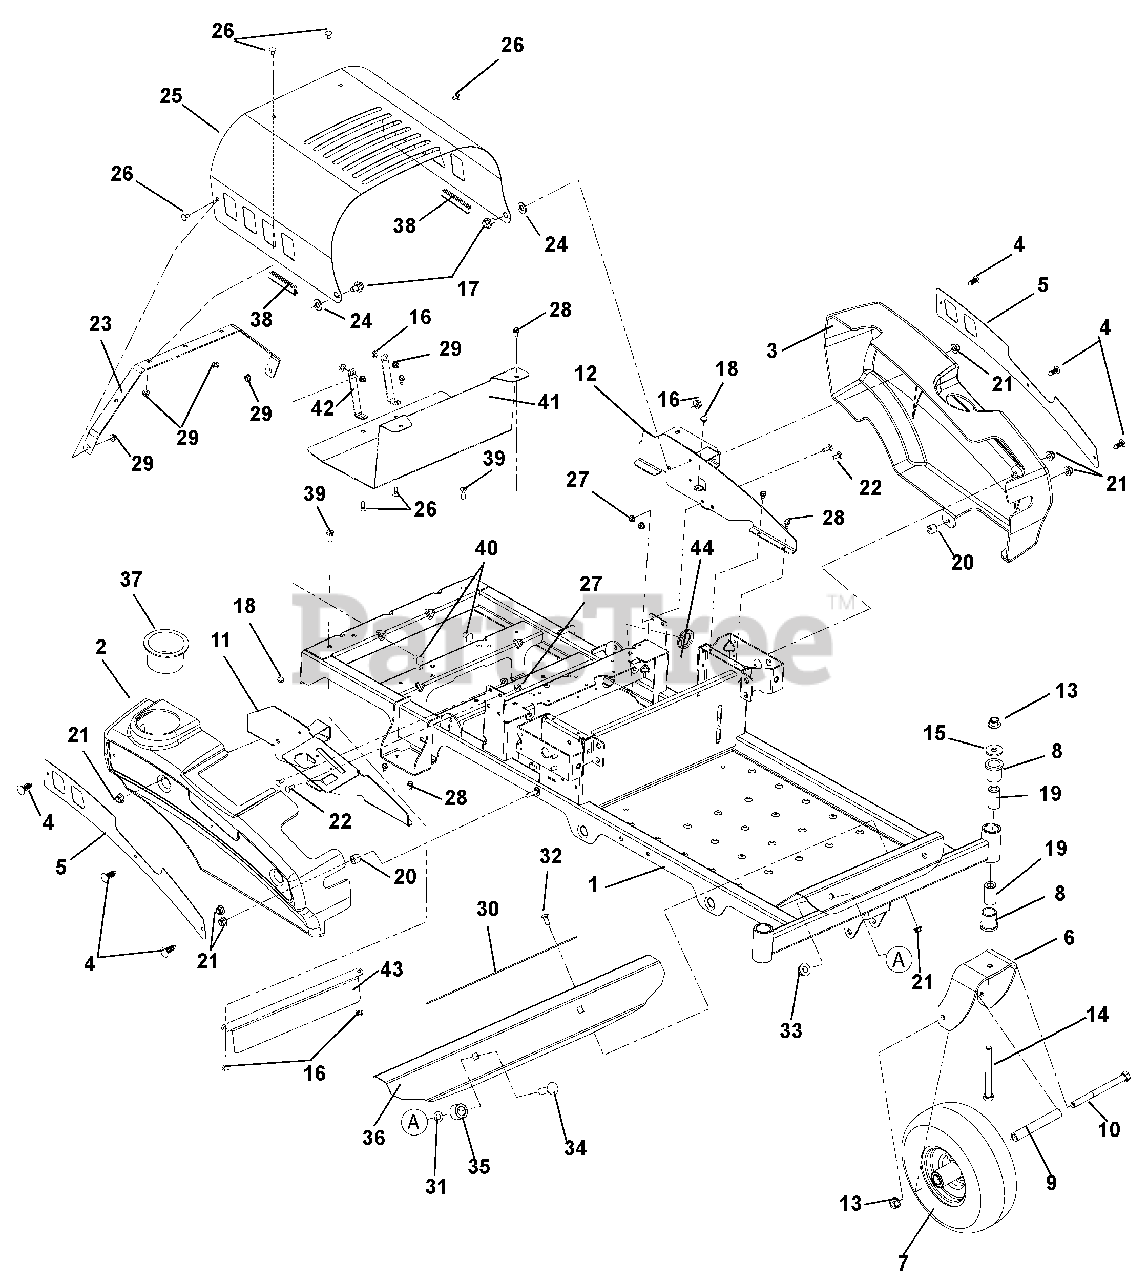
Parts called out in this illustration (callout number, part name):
1	FRAME, WELDMENT ZOOM 2012
2	FENDER, RH
3	FENDER, LH
4	RIVET, .25 NYLON PANEL
5	PLATE, FENDER
6	WMT, CASTER FORK
7	TIRE/WHEEL ASSY, 11X4-5
8	BSHG-FLG 1.00X1.25X1.50X1.50
9	SPACER, ROLLED WHEEL
10	@BLT-HEX .50-13X6.50 GR5 YWZC
11	WLDMT, RH FENDER MOUNT
12	WLDMT, LH FENDER MOUNT
13	@NUT-LK-TOP-FLG .50-13 YWZC
14	@BLT-HEX .50-13X5.00 GR5 YWZC
15	WSHR-FL-STL.511X1.441X.125 YWZ
16	@NUT-LK-TOP-FLG .38-16 YWZC
17	BOLT-SHLDR .375-16X.150
18	BUMPER GROMMET
19	SPACER, CASTER .50X1.00X1.84
20	BSHG-SLV .391X.688X.52 PM
21	@NUT-LK-NYL-FLG .31-18 YWZC
22	@BLT-RDHDSQNK .25-20X.75 G5YZ
23	BRACE, HOOD
24	WSHR-FL-NYL .518X1.000X.080
25	HOOD, ZOOM
26	@BLT-RDHDSQNK .25-20X.50 G5YZ
27	@NUT-LK-NYL-FLG .25-20 YWZC
28	SCR-TAP .25-20X.50 HWH TR YWZ
29	@NUT-LK-TOP-FLG .25-20 YWZC
30	GRIP, ADHESIVE (1" X 16" BLK)
31	NUT-PUSH, .50
32	@BLT-RDHDSQNK .31-18X.75 G5YZ
33	@NUT-LK-NYL-FLG .50-13 YWZC
34	@BLT-RDHDSQNK .50-13X1.75 G5YZ
35	TUBE, UPPER CONTROL PIVOT
36	FOOTREST
37	CUPHOLDER, SNAP-IN 3.75OD
38	EDGING, CLUTCH PADDLE - 2.00"
39	@BLT-HEX .38-16X1.00 GR5 YWZC
40	@BLT-RDHDSQNK .38-16X1.00 G5YZ
41	GUARD, HEAT SHIELD (ZOOM/ZT)
42	STRAP, HEAT SHIELD (ZOOM/ZT)
43	GUARD, HOT SURFACE (ZOOM/ZT)
44	GROMMET 1.0ID X 1.38 OD
